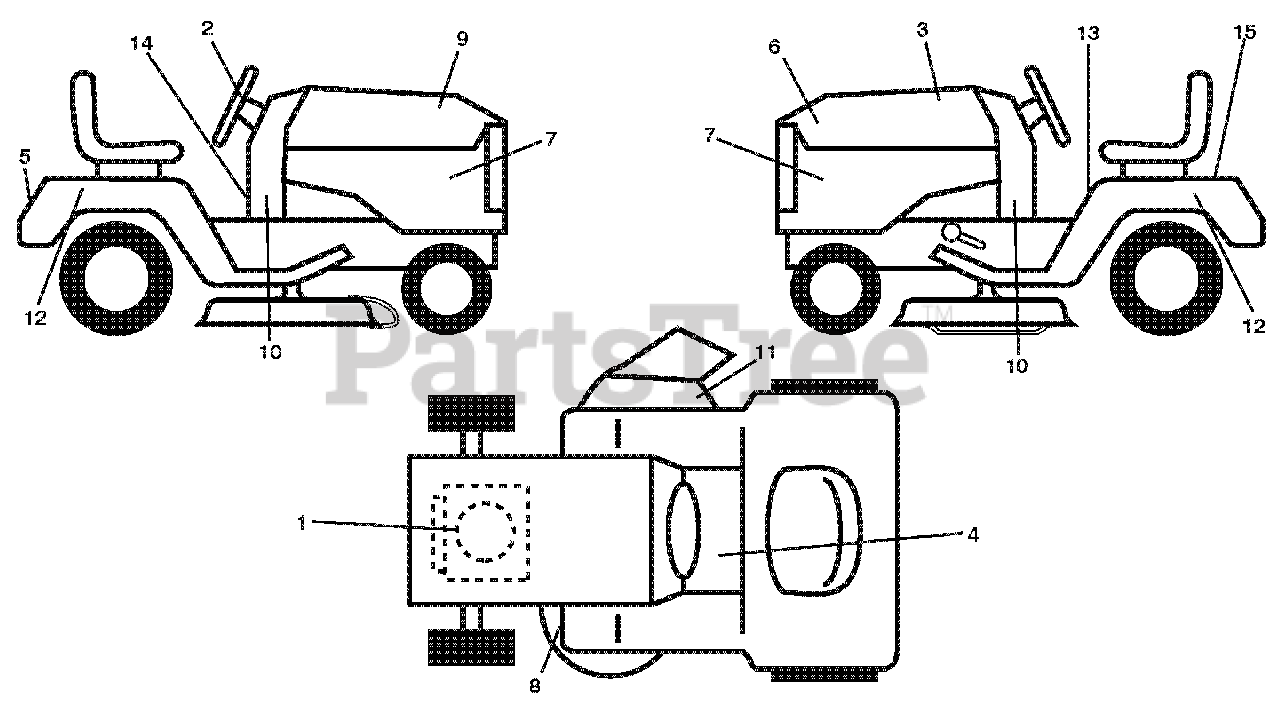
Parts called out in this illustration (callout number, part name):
1	DECAL, REPLACEMENT
2	Decal, Ins Str Wh
3	DECAL.REPLACEMENT
4	DECAL.FENDER
5	DECAL.FENDER.REAR.ARIENS
6	DECAL.HOOD.LH
7	DECAL.SDPNL.PWRDBY B&S.ARIENS
8	DECAL.V-BELT.SCH.42/46"MEC/ELE
9	DECAL.HOOD.RH
10	DECAL, DASH LOWER
11	DECAL.MOWER.WARN.KEEP HAND AWY
12	DECAL.FENDER.SD.GEAR.DR
13	DECAL, WARNING START INST.
14	Decal, Spark Arrester
15	DECAL.BAT.DAN/POI P/L SYM.WPN
